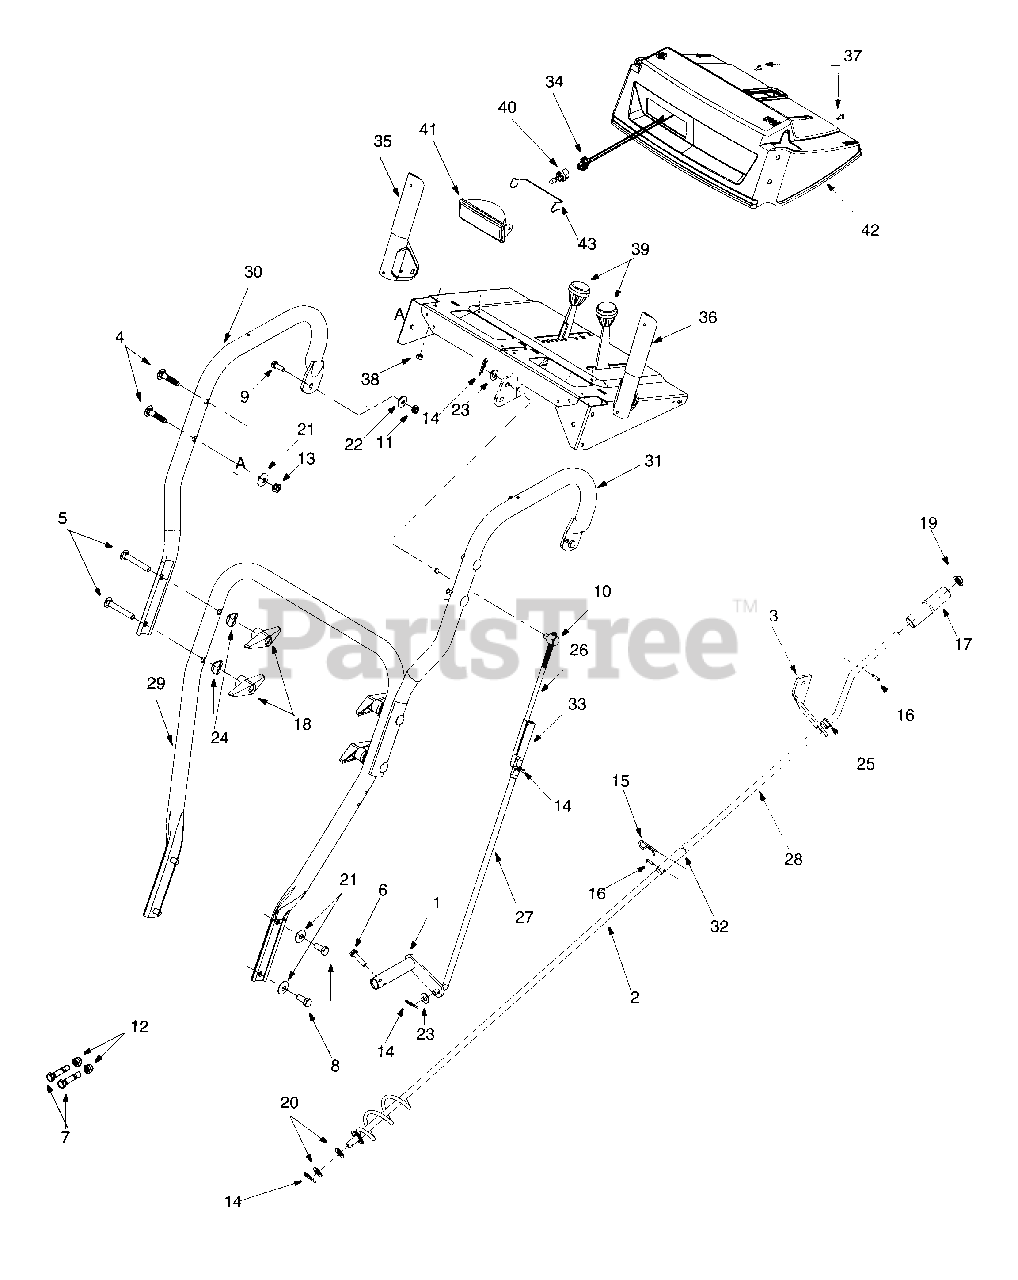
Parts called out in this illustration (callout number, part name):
1	Shift Arm Assembly
2	Chute Crank Assembly
3	Chute Crank Bracket
4	Carr. Bolt 5/16-18 x 1.5
5	Carr. Screw 5/16-18 x 2.25 Gr.5
6	Hex Washer Head TT Screw 1/4-20 x 1.0
7	Shear Bolt 5/16-18 x 1.5
8	Hex Bolt 5/16-18 x 0.75 Gr.5
9	Hex Bolt 1/4-20 x 0.75 Gr.5
10	Ferrule
11	Hex Nut: 1/4-20
12	Hex Lock Nut
13	Hex Nut: 5/16-18
14	Cotter Pin
15	Click Pin
16	Roll Pin
17	Chute Crank Knob
18	Wing Nut
19	Push Cap
20	Flat Washer
21	Belleville Washer
22	Bell Washer
23	Flat Washer
24	Saddle Washer
25	Plastic Bushing
26	Shift Rod: Upper
27	Shift Rod: Lower
28	Chute Crank: Upper
30	Handle: C Style RH
31	Handle: C Style LH
32	Spacer
33	Clutch Rod Connector
34	Harness, Halogen Light
35	Handle Engagement Assembly: RH Black
36	Handle Engagement Assembly: LH Black
37	Hex washer Hd. Sp. screw
38	Hex Sems Nut
39	Shift Knob
40	Halogen Lamp
41	Lamp Housing
42	Handle Panel: yellow w/Tilt, Light
43	Halogen Retainer: Handle
